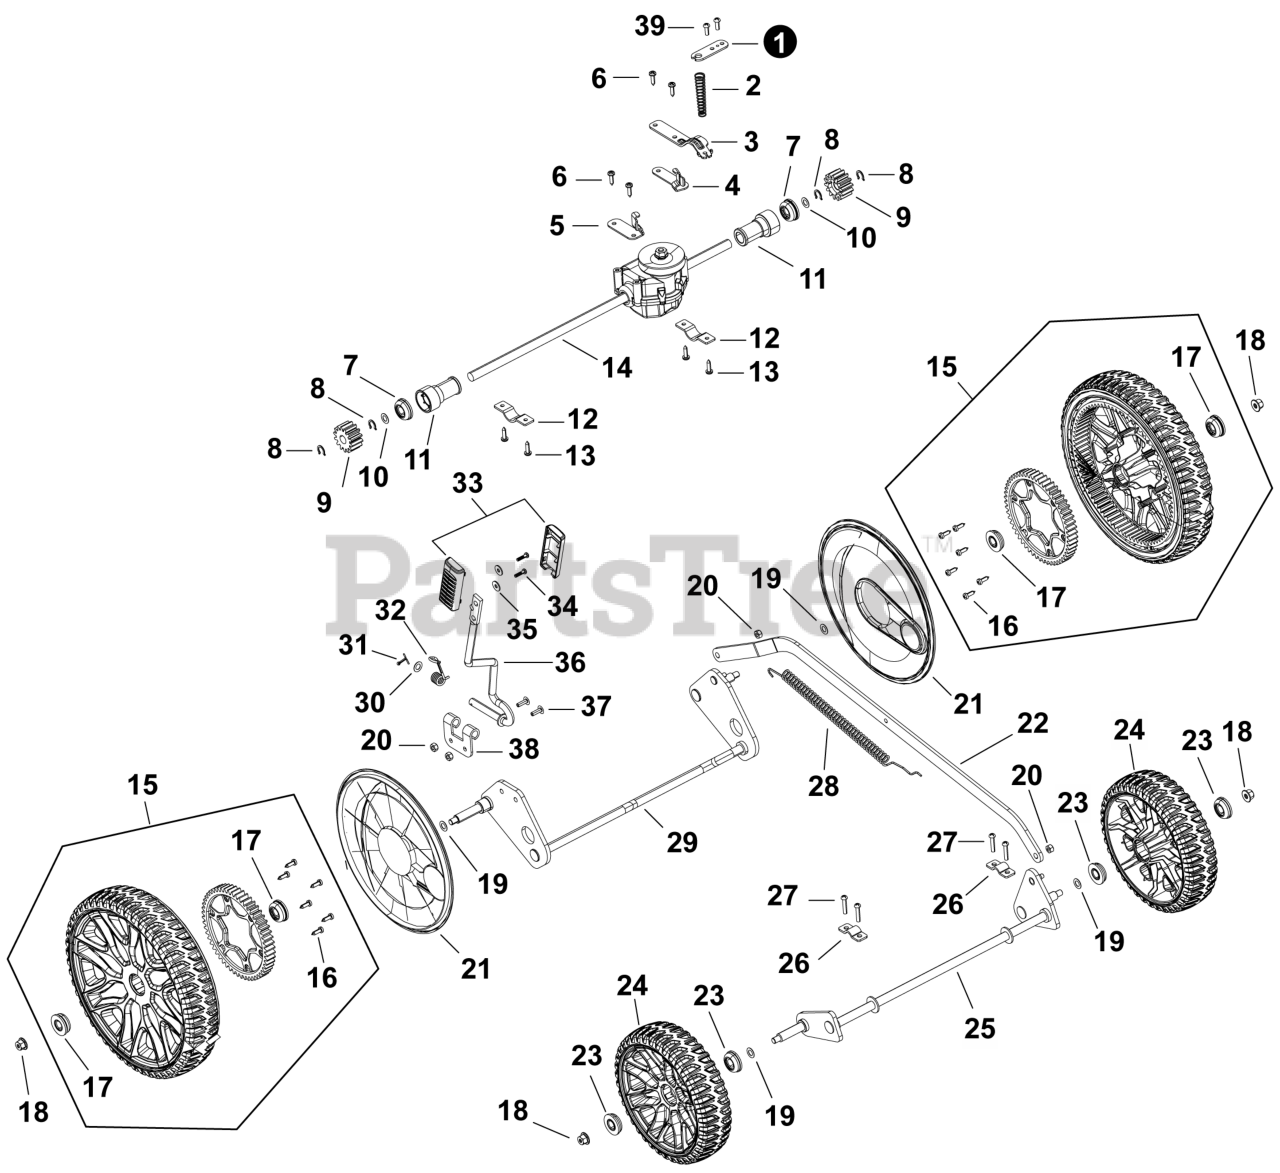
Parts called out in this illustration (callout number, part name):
1	PLATE, CABLE MOUNTING
2	SPRING, DRIVE CABLE
3	PLATE, CABLE ADJUSTMENT
4	BELT GUARD, REAR LEFT
5	BELT GUARD, REAR RIGHT
8	RING, RETAINING
9	GEAR, DRIVE
11	SLEEVE, SHAFT
12	BRACKET, AXLE RETAINER
14	ASSY, TRANSMISSION
15	WHEEL, ASSY., REAR
15	WHEEL ASSY., REAR
16	SCREW
17	BEARING
19	COVER, DUST
20	ROD, HEIGHT ADJUSTMENT
21	COVER, DUST
21	WHEEL ASSY., FRONT
22	ROD, HEIGHT ADJUSTMENT
22	AXLE, FRONT
23	BRACKET, AXLE RETAINER
24	WHEEL, FRONT
25	AXLE, FRONT
26	BRACKET, AXLE RETAINER
26	AXLE, REAR
29	AXLE, REAR
30	COVER KIT, HEIGHT ADJ. HANDLE
33	COVER KIT, HEIGHT ADJ. HANDLE
33	HANDLE, HEIGHT ADJUSTMENT
35	PLATE, HEIGHT ADJ. HANDLE
36	HANDLE, HEIGHT ADJUSTMENT
38	PLATE, HEIGHT ADJ. HANDLE
